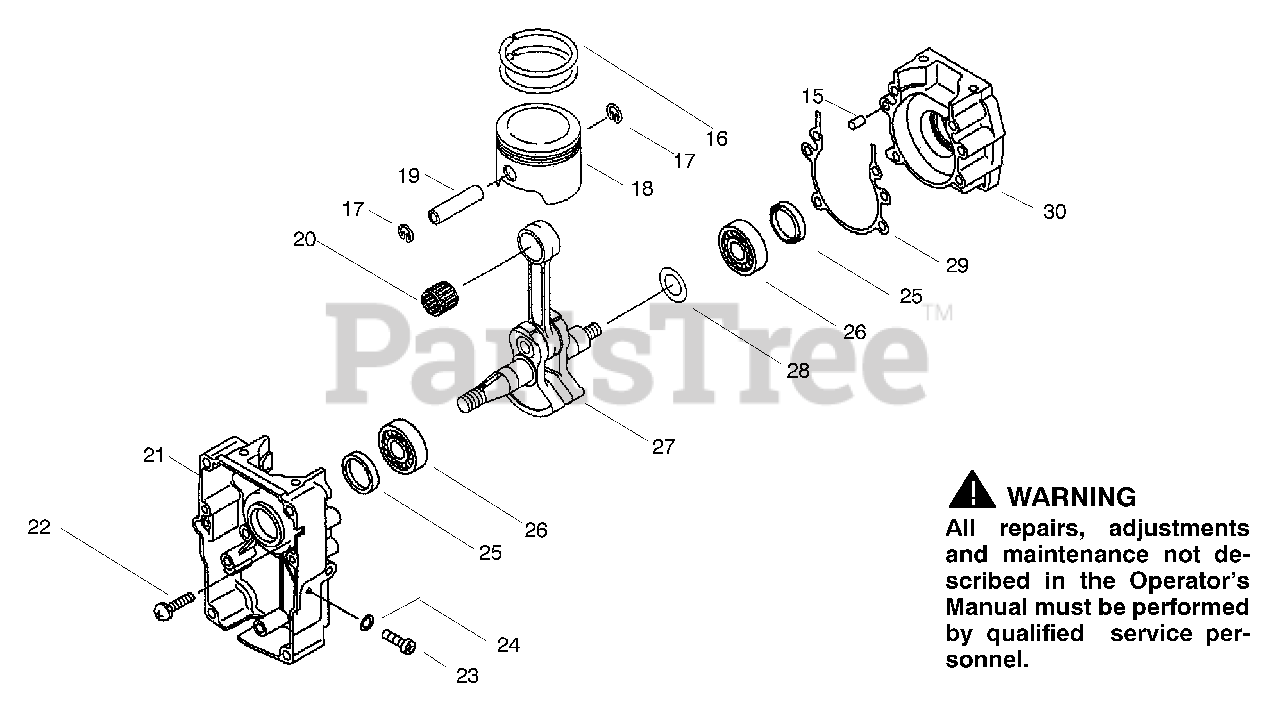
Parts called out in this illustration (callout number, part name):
15	Pin-Dowel
16	Ring-Piston Set
17	Ring-Snap
18	Piston-Engine
19	Pin-Piston
20	Bearing-Needle
21	Crankcase
22	Screw-Pan-WS
23	Screw-Pan
25	Seal-Oil
26	Bearing-Ball 6202C3
27	Assy-Crankshaft
28	Shim-T=0.10
28	Shim-T=0.20
28	Shim-T=0.40
28	Shim-T=0.60
29	Gasket-Crankcase
30	Crankcase
